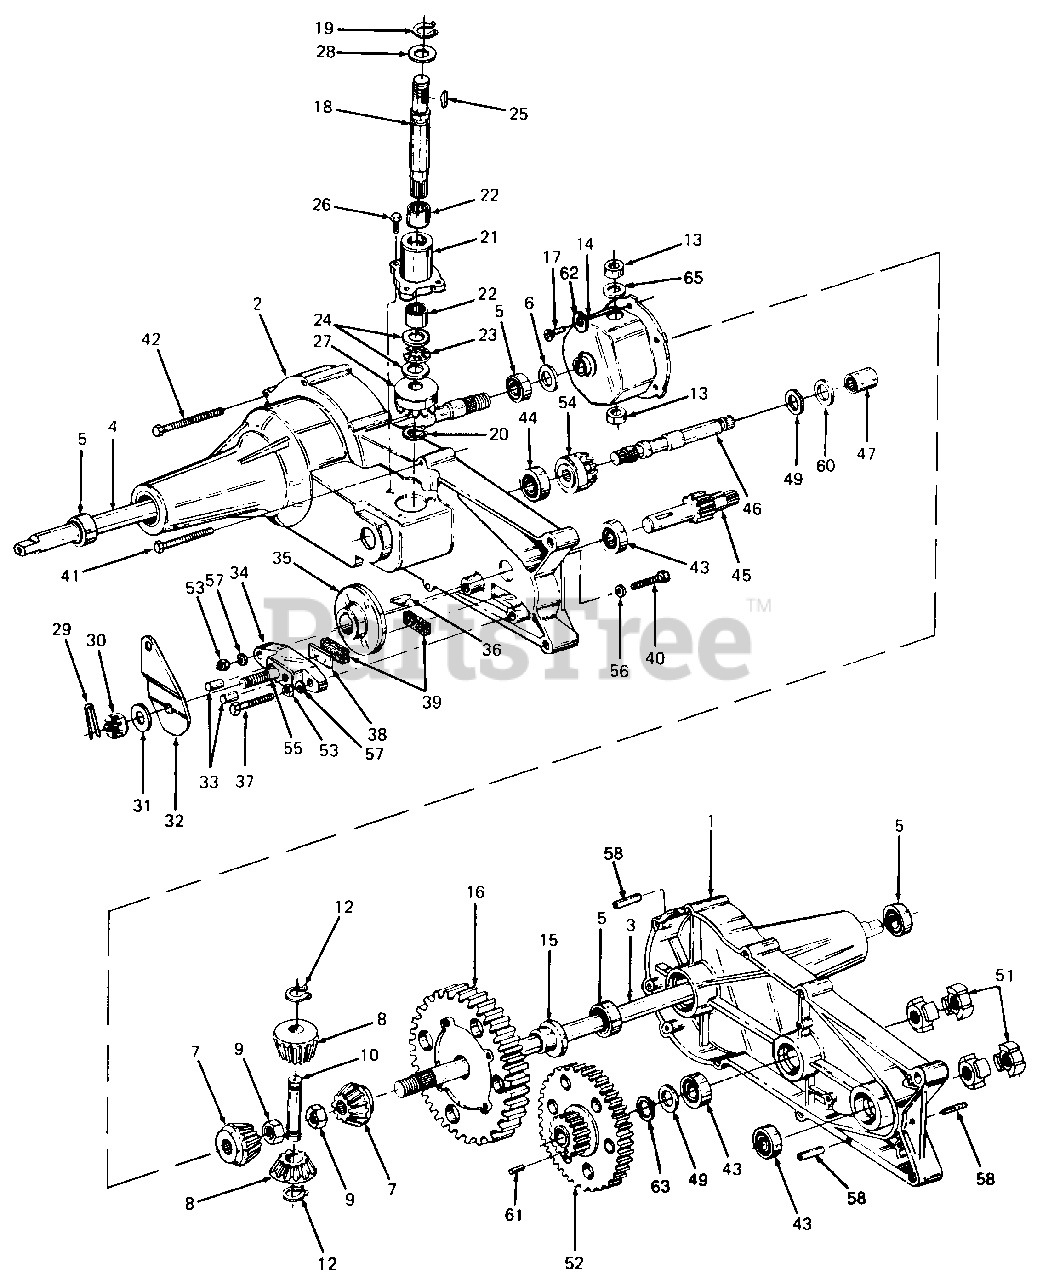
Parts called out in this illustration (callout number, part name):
1	Housing Half, L.H.
2	Housing Half, R.H.
5	Bearing, Ball
6	Washer, Flat, .76" x 1-1/8" x .306" Thk. Hdn.
7	Gear, Miter
9	Nut, Hex Jam Patch Lock 1/2-20
10	Shaft, Cross
12	Ring, Snap
13	Bearing, Thrust
14	Housing Ass'y. Differential
15	Bearing, Flange, .75" I.D. x .587"
16	Gear, Differential, 72 Tooth
17	Torx Hd. AB-Tap Scr. 1/4 x .62" Lg.
18	Shaft, Input
19	Ring, Snap
20	Ring, Retaining, Ext. 7/16" Dia.
21	Bearing, Input Housing
22	Bearing, Needle, 5/8" I.D. x .50" Lg.
23	Bearing, Thrust
24	Washer, Flat, 5/8" I.D. x 1.12" O.D. x .030" Thk.
25	Key #4 Hi-Pro, 3/32" x 5/8" Dia. (Hdn)
26	Screw, Hex Patch Lock, 1/4-20 x 3/4" Lg.
27	Gear, Input Pinion, 17 Tooth
28	Washer, Flat, .62" I.D. x 1.0" O.D. x .030" Thk.
30	Nut, Castle, 5/16-24 Thd.
31	Washer, Flat, .343" x .88" x .062" Thk.
32	Arm, Brake Actuator
33	Pin, Actuating, 5/16" Dia.
36	Key, Hi-Pro, 3/16" x 5/8" Dia.
37	Screw, Hex Patch Lock, 1/4-20 x 1.5" Lg.
38	Plate, Puck
39	Puck, Brake
40	Screw, Hex Cap, 1/4-20 x 1.5" Lg.
41	Screw, Hex Self-Tap, 1/4-20 x 2.0" Lg.
42	Screw, Hex Self-Tap, 1/4-20 x 2.75" Lg.
43	Bearing, Ball
44	Bearing, Ball
45	Shaft, Pinion w/11 Tooth Gear
46	Shaft, Drive
47	Bearing, Needle
49	Washer, Flat, 5/8" x 1.12" x .060" Thk.
51	Coupling
52	Gear, Tooth 60 & 17
53	Nut, Hex Jam, 1/4-20 Thd.
54	Gear, Drive Pinion, 17 Tooth
55	Bolt, Square Hd. 5/16-24 Thd.
56	Washer, Flat, .265" x .938" x .12" Thk.
57	Washer, Lock, 1/4" I.D.
58	Pin, Roll, 3/16 Dia. x .50" Lg.
60	Bronze Thrust Brg. 5/8" I.D.
61	Dowel Pin 3/32" x 1/4"
62	Washer, Spring Lock 1/4" I.D.
63	Seal, Grease
65	Washer, Flat, .62" I.D. x 1.0" O.D. x .020" Thk.
